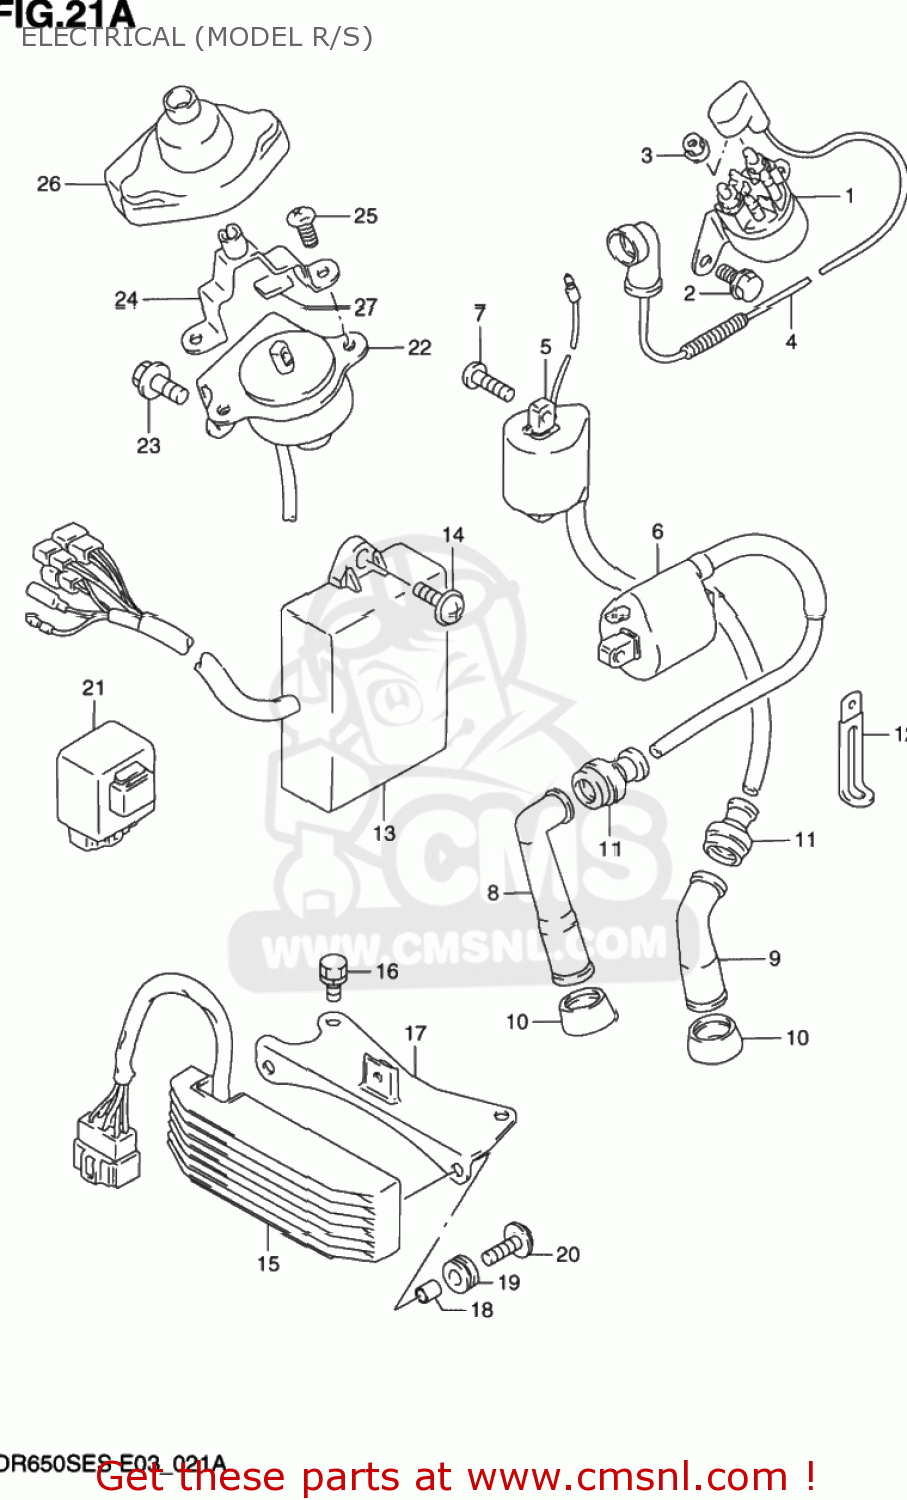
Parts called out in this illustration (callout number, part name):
1	RELAY ASSY,STARTING MOTOR
2	BOLT
3	NUT
4	WIRE,STARTER MOTOR LEAD
5	COIL ASSY,IGNITION
6	COIL ASSY,IGNITION
7	SCREW, 6X20
8	CAP ASSY,SPARK PLUG
9	CAP,SPARK PLUG
10	SEAL,SPARK PLUG CAP
11	SEAL,HIGH TENSION CORD
12	CLAMP
13	CDI UNIT
14	SCREW
15	RECTIFIER ASSEMBLY
16	BOLT
17	BRACKET,RECTIFIER
18	SPACER (6.1X8X9.5)
19	CUSHION
20	SCREW(6X20)
21	CONTROL UNIT,DECOMP
22	SOLENOID ASSY,DECOMP
23	BOLT
24	HOLDER,DECOMPRESSION CABLE
25	SCREW
26	COVER,DECOMP
27	CUSHION
